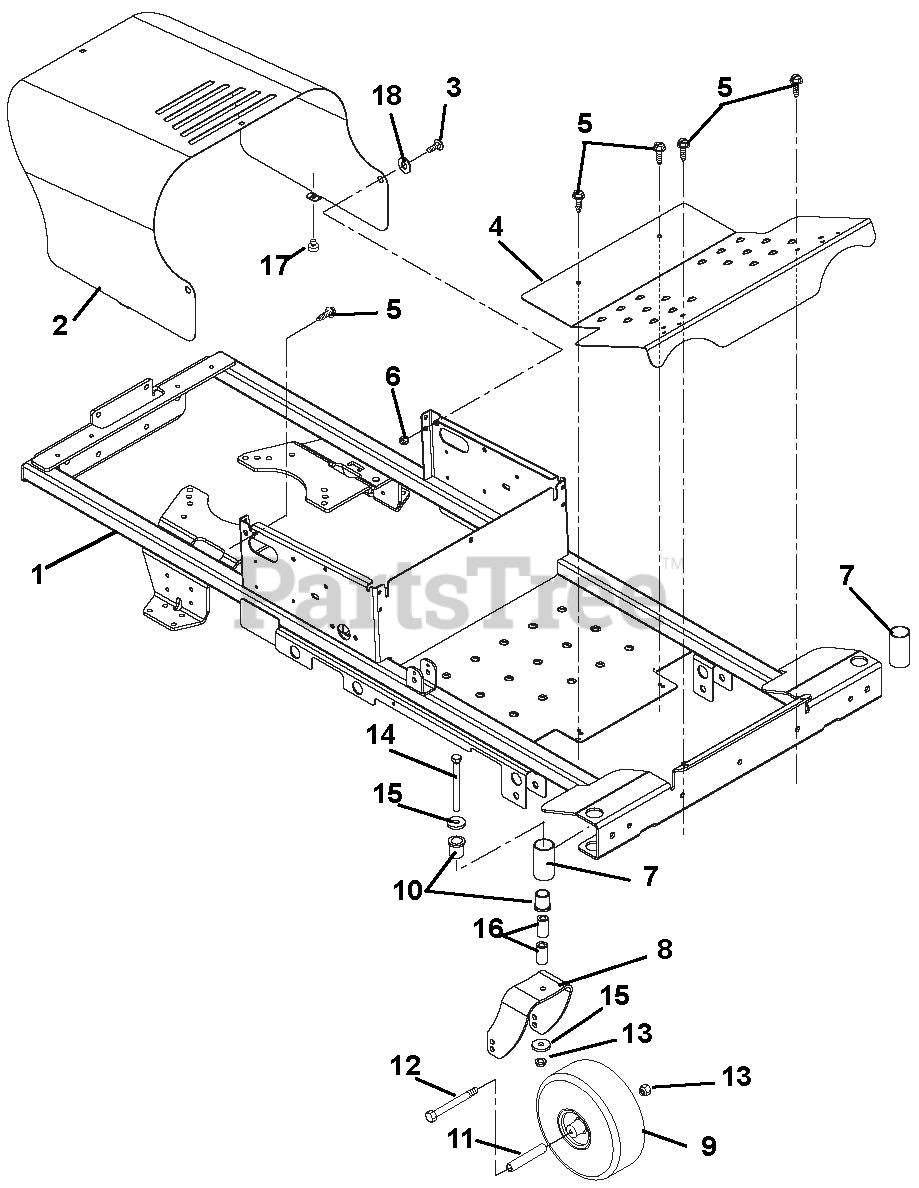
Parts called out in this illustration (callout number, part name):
1	Weldment, MZ Frame
2	Engine Cover
3	Bolt, Shoulder .375-16 x .135
4	Footrest, MZ/MZT
5	Screw, Tapping .31-18 x .50
6	Nut, Locking Top Flange .38-16
7	Sleave, Caster
8	Fork, Caster
9	Assembly, Tire 4 x 11- 2 Ply
10	Bushing, Flange 1.00 x 1.25 x 1.50 x 1.50
11	Spacer, Wheel
12	Bolt, Hex .50-13 x 6.50 Grade 5
13	Nut, Locking Top Flange .50-13
14	Bolt, Hex .50-13 x 5.00 Grade 8
15	Washer, Flat Steel .515 x 1.625 x .250
16	Spacer, Caster
17	Button Bumper
18	Washer, Flat Nylon .518 x 1.000 x .080
